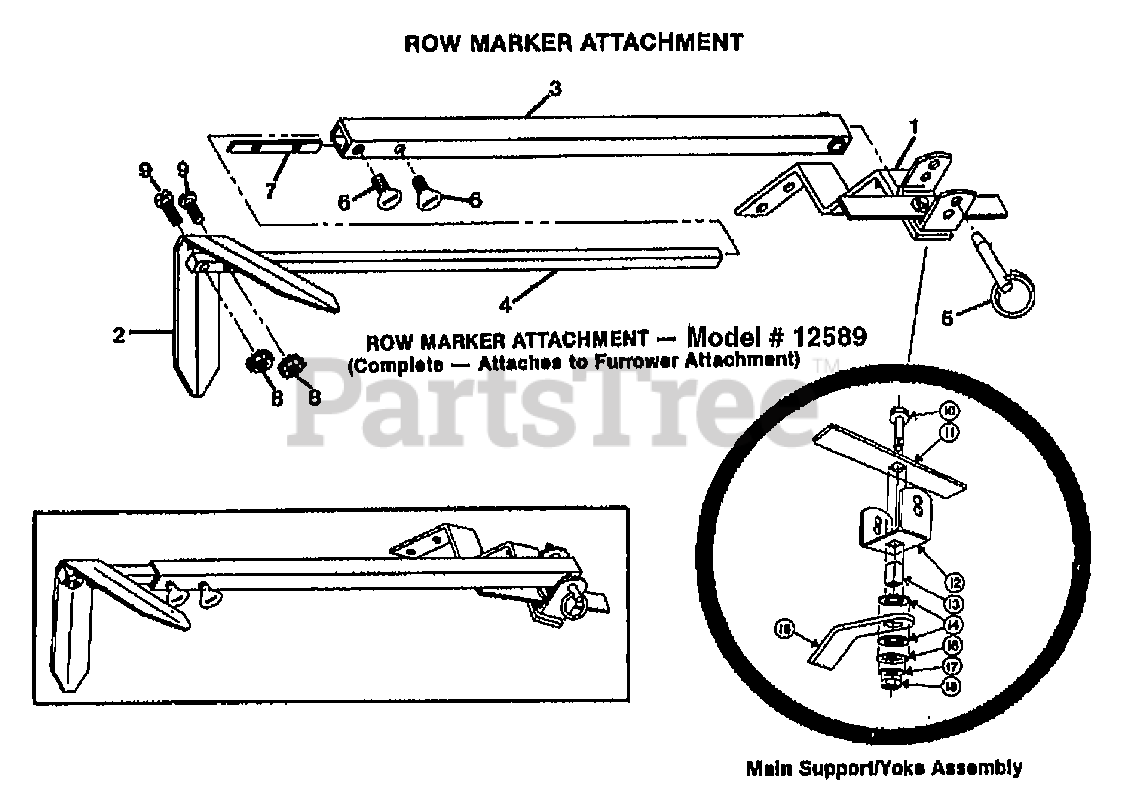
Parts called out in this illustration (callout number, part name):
1	MAIN SUPPORT ASSY
2	MARKER-ROW MARKER
3	MARKER ARM
4	MARKER ARM EXTENSION
5	PIN # COTTERLESS HITCH ZP
6	SCR-THUMB 1/4-20 X .75 ZP
7	BAR-NUT
8	NUT W/LKWASHER 10-24 ZP
9	SCR-RH M10-24X1.0 NC-2A
10	SCR-HFLK 3/8-16X1.50
11	BAR-STOP
12	YOKE-ROW MARKER
13	TUBING-SQ .5 X .907
14	WASHER-.375X.51X.125
15	SUPT-MAIN ROW MARKER
16	WASHER-SQ HOLE 1.38X5SQX.12
17	WASHER-.994X.413X.145
18	NUT-HEX 3/8-16 ZP
